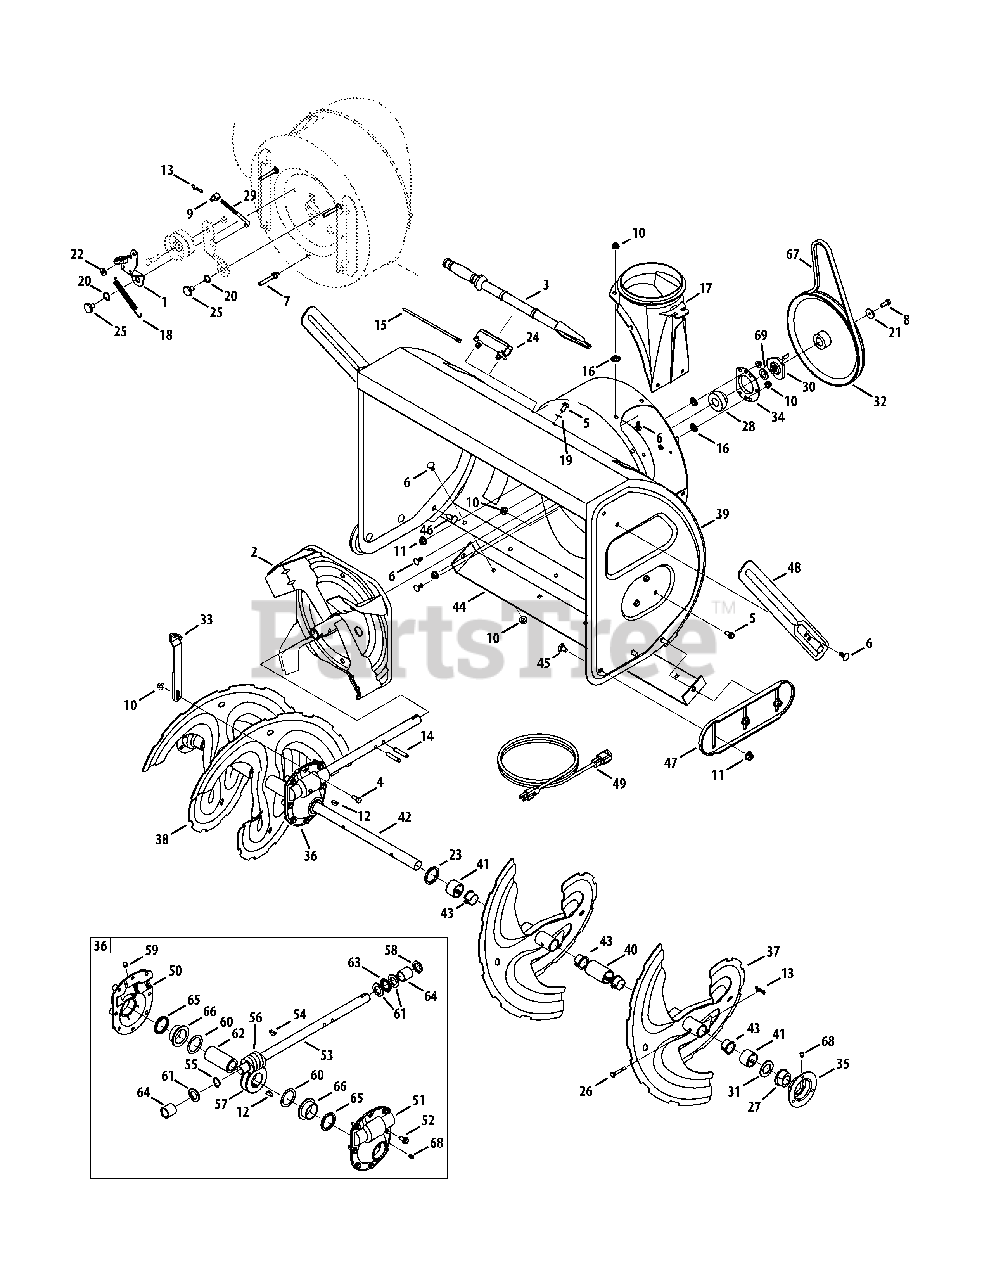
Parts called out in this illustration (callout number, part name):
1	Bracket Assy, Auger Brake
2	Impellar, 16"
3	Tool, Cleanout
4	Scr,Hex Cap, 5/16-18 x 1.00
5	Screw, 5/16-18 x .750
6	Screw, Carriage, 5/16-18 x .75
7	Screw, 5/16-18 x .4300
8	Screw, 5/16-24 x .875
9	Ferrule
10	Nut, Flnge Lk, 5/16-18
11	Nut, Flg Lk, 3/8-16
12	Key, Woodruff,1/4 x 3/4
13	Pin, Bowtie Cotter
14	Pin, Spirol, 5/16 x 1.75
15	Tie, Cable
16	Nut, Push
17	Adapter, Chute, 6"
18	Spring, Extension
19	Washer, .349 x .879 x .063
20	Washer, .625 x .885 x .015
21	Washer, Flat, .34 x 1.50 x .150
22	Washer, .344 x .75 x .12
23	Washer, 1.01 x 1.86 x .06
24	Clip, Mounting
25	Screw, Shoulder, .625 x .17
26	Pin, Shear, .25 x 1.75
27	Bearing, Flange w/Flats
28	Bearing, Self Aligning
29	Rod, Auger Idler
30	Pulley, Adapter, .75 Dia.
31	Spacer, 1.004 x 1.375 x .25
32	Pulley, Auger Drive, 10.0
33	Bracket, Gear Box Support
34	Housing, Bearing
35	Housing, Bearing
36	Gear Box Assembly, Auger
37	Spiral Assy, LH
38	Spiral Assy, RH
39	Housing, Auger - 33"
40	Spacer, 1.0 x 1.5 x 2
41	Spacer, 1.0 x 1.5 x 1
42	Axle, Spiral, 33"
43	Bushing, Flange, 1.051 x 1.16
44	Shave Plate
45	Bolt, Carriage, 3/8-16 x .750
46	Bolt, Carriage, 3/8-16 x 1.0
47	Shoe, Skid
48	Drift Cutter
49	Extension Cord, 110V
50	Hsg Assy Auger RH (Inc. 65 & 66)
51	Hsg Assy Auger LH (Inc. 65 & 66)
52	Screw, LD, 5/16-18 x .750
53	Shf, Drive, Auger
54	Key, Hi Pro, 3/16 x 3/4
55	Ext, Ret, Ring
56	Gear, Worm, Dbl Thread
57	Gear, Worm, LH
58	Seal, Oil
60	Washer, Flat, 1.52 ID x 2.0 OD
61	Washer, Flat, .88 ID x .38 OD
62	Shf, Gear, Worm
63	Brg, Thrust
64	Sleeve
65	Oil Seal
66	Flange Bearing
67	V Belt,4L x 44.60 Lg.
68	Lube Fitting, 3/16 #70
69	Washer, Flat, .78 x 1.49 x .08
